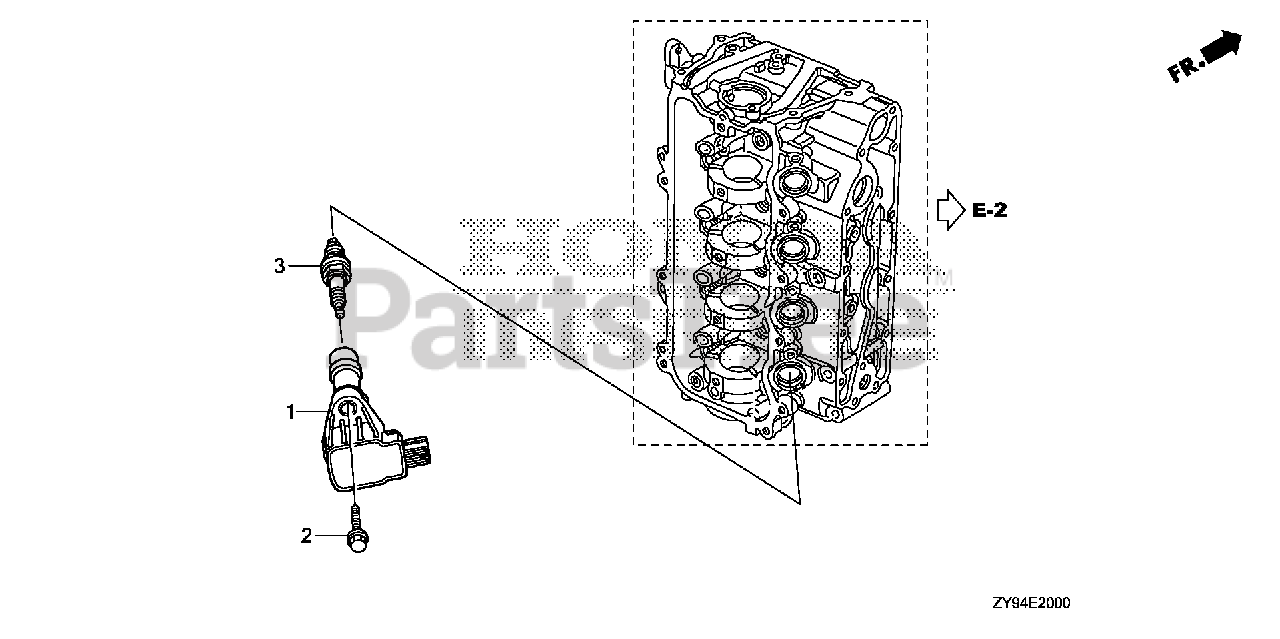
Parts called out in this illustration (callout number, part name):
1	COIL ASSY., PLUG TOP
2	BOLT, FLANGE (6X25)
3	SPARK PLUG (IZFR6K-11E) (NGK)
